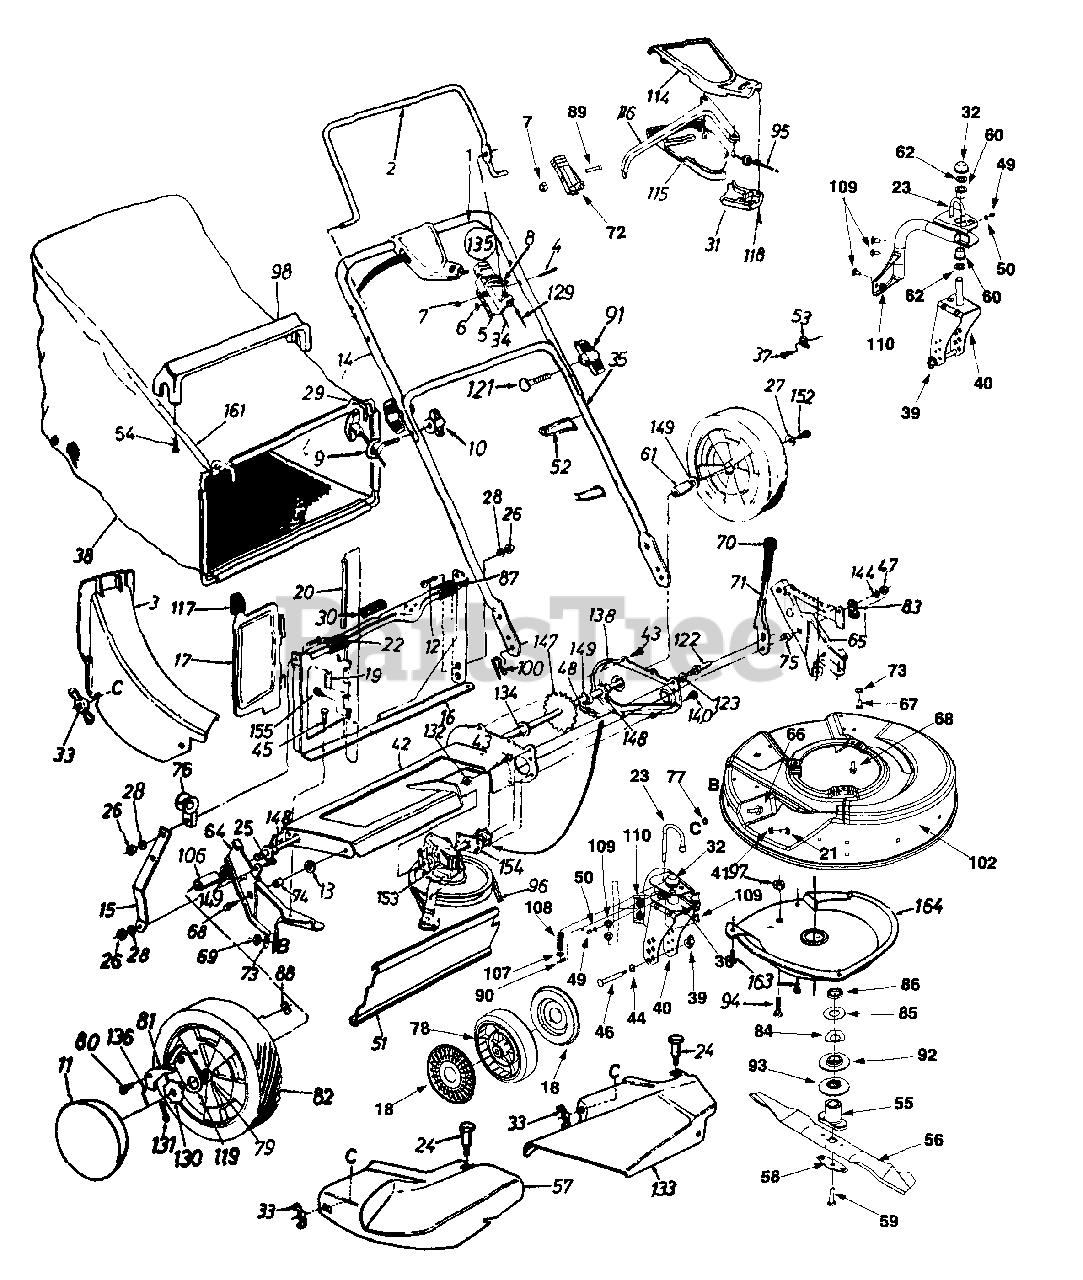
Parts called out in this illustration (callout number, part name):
1	Foam Handle
3	Rear Discharge Chute Ass'y
4	Oval C-Sunk Screw
5	Throttle Body
6	Spring Washer .66"
7	Hex L-Nut 1/4-20
8	Throttle Lever
9	Rope Guide
10	Wing Nut 1/4-20
11	Hub Cap Spoke
12	Truss Machine Screw 1/4-14 x .625
13	Flat Washer .383" ID x 1" OD
19	Torsion Spring
20	Pivot Pin
21	Carriage Bolt 1/4-20 x .62"
22	Truss Machine Screw 1/4-20 x .75"
23	Lock Pin
24	Shoulder Bolt .312 x .18
25	Hex Bolt 1/4-20 x .62"
26	Hex Nut 1/4-20
27	Bell Washer 1/4"
28	Lock Washer 1/4"
30	Foam Strip
31	SP Control Cover
32	Push Cap
33	Wing Nut w/Washer
34	Throttle Control Wire 61"
37	Hex Tap Screw #10-32 x .62"
38	Grass Bag
39	Wing Nut
41	Flat Washer .344" ID x .62"
44	Wave Washer
45	Hex Tap Screw 1/4 x .62"
46	Caster Axle
47	Hex Lock Nut 3/8-24
48	#48 Chain .500" Pitch x 30 Links
49	Lube Fitting
50	Flat Washer
51	Rear Flap
52	Cable Tie
53	Cable Clamp
54	Hex Screw #12 x 1.25"
55	Blade Adapter Kit
56	21" Standard Blade
56	21" Mulching Blade
57	Mulching Plug
58	Blade Bell Support
59	Hex Bolt 3/8-24 x 1.5"
60	Flange Bearing
61	Spacer .513" ID x .69"
62	Flat Washer 5/8 ID x 1.0 OD
67	Hex Tap Screw 5/16-18
68	Hex Tap Screw 3/8-16
69	Hex Nut 5/16-18
71	Height Adjuster Lever
72	Throttle Housing w/o Lever
73	Bell Washer 5/16"
74	Spacer
75	Shoulder Spacer .50"
76	Rope Guide
77	Bolt Retainer
78	Front Wheel Ass'y Comp
79	Bearing 1/2" ID
80	Shoulder Screw
81	Pawl
82	Rear Wheel Ass'y Comp
83	Clamp
84	Flat Washer
85	Spring Washer .89" ID
86	Crankshaft Spacer
87	Panel Clip
88	Weld L-Nut 1/4-20
89	Screw 1/4-20 x 20
90	Cotter Pin
91	Hand Knob
92	Pulley Half-Upper
93	Pulley Half-Lower
94	Machine Screw 1/4-20
95	Sp Cable
96	V-Belt
97	Sems Nut 1/4-20
98	Bag Handle
100	Hairpin Clip
107	Flat Washer .330 ID x .630 OD
108	Compression Spring
109	Carriage Bolt 5/16-18 x .62
110	Flange Lock Nut 5/16-18
114	SP Control Cover
115	SP Control Cover
116	Control Lever
117	Door Grip
118	C Sunk Head Tap Screw #10-16 x .625
119	Pawl Plate
121	Curved Carriage Bolt 5/16-18 x 2"
122	Shoulder Pin 3/8-24 x 1.43"
123	Lock Washer 3/8" ID
129	Control Cable
130	Ratchet Wheel 1.62" OD
131	Cotter Pin
132	Hex Jam Nut 3/8-24
133	Side Chute Deflector Ass'y
134	Hex Flange Bearing
135	Throttle Box Comp
136	Nylon Spring
144	Flat Washer
147	Rear Shaft Ass'y
148	Hex Flange Bearing .506" ID
149	Flat Washer .531" x .930"
152	Hex Bolt 1/4-20 x .62
153	Transmission Comp
155	Hex Tap Screw #10 x .38
163	Hex Tap Screw 1/4 x .38"
